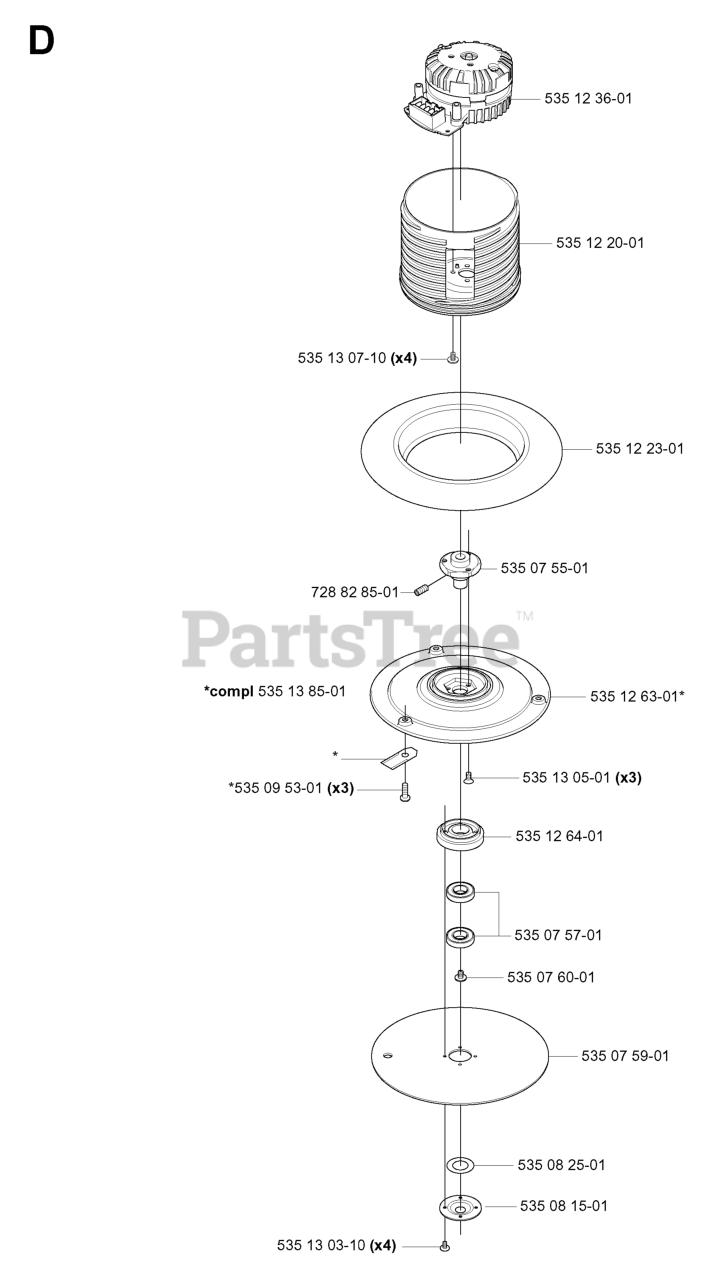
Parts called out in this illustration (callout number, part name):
2	MUFFLER.TWIN.CYL.LOW.TONE
8	RP.IDLER GROOVED
9	KEEPER ASM BELT ENGINE
12	PULLEY ENG VGT ELECT CLUTCH
15	FUEL TANK 3.5G
16	PAD IDLER TI
17	PAD-SPACER LT
18	CAP, FUEL GUAGE
20	THROTTLE CABLE
21	SCREW
22	REPL BY 532 1754-40
24	LOCKWASHER
25	Nut Keps 3/8 - 24 UNF
26	BUSHING OUTLET T
27	STEM FUEL TANK
28	FUEL LINE
29	KIT.SPARK ARRESTOR 794945 B&S
35	WASHER.LOCK.HVY.HLCL.SPR.5/16
37	HOSE CLAMP
39	SCREW TT 3/8-16X2-1/4 UNC
40	Screw TT 3/8-16 x 4 unc
42	LOCKWASHER
43	BOLT HEX 7/16-20X4-1/4"
45	NUT
62	RP SHIELD HEAT MUFFLER
69	GASKET.MUFFLER
70	TUBE.EXHAUST.B&S.VGT.LH
71	TUBE.EXHAUST.B&S.VGT.RH
74	ELBOW STREET BRASS
79	SCREW
81	TUBE, DRAIN OIL ASM.
82	PLUG, OIL DRAIN EASY
83	BOLT.5/16-18UNCX3/4 W/SEMS.BLK
84	SCREW 3/8-16 X 1-1/2
